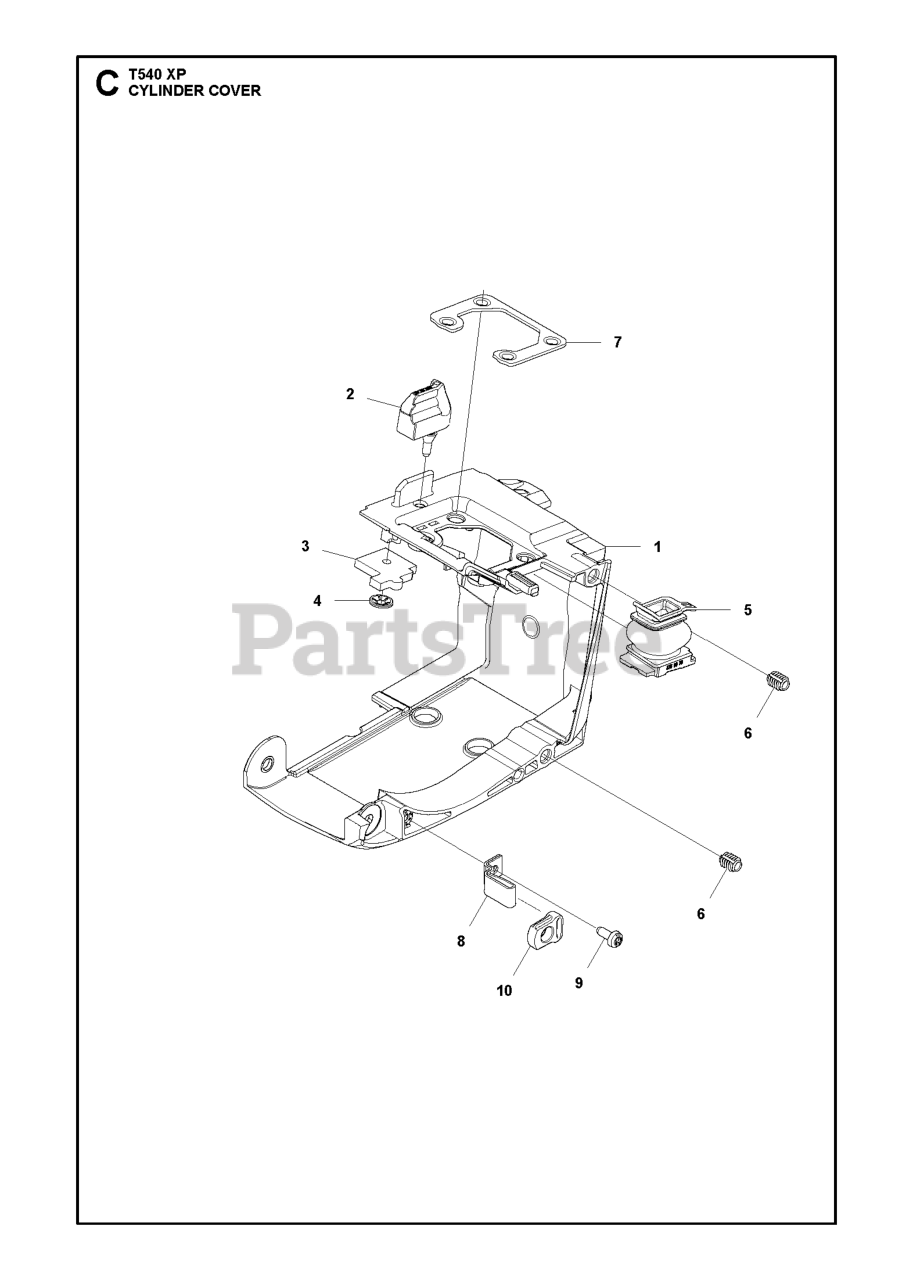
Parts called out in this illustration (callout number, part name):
1	RP_CYLINDER COVER ASSY
4	LOCK WASHER
6	THREAD INSERT
7	PLATE CYLINDER COVER
8	STRAP ANTIVIBRATION FRONT HAND
9	SCREW CITXPANT
10	WEDGE DEFLECTION LIMITER
